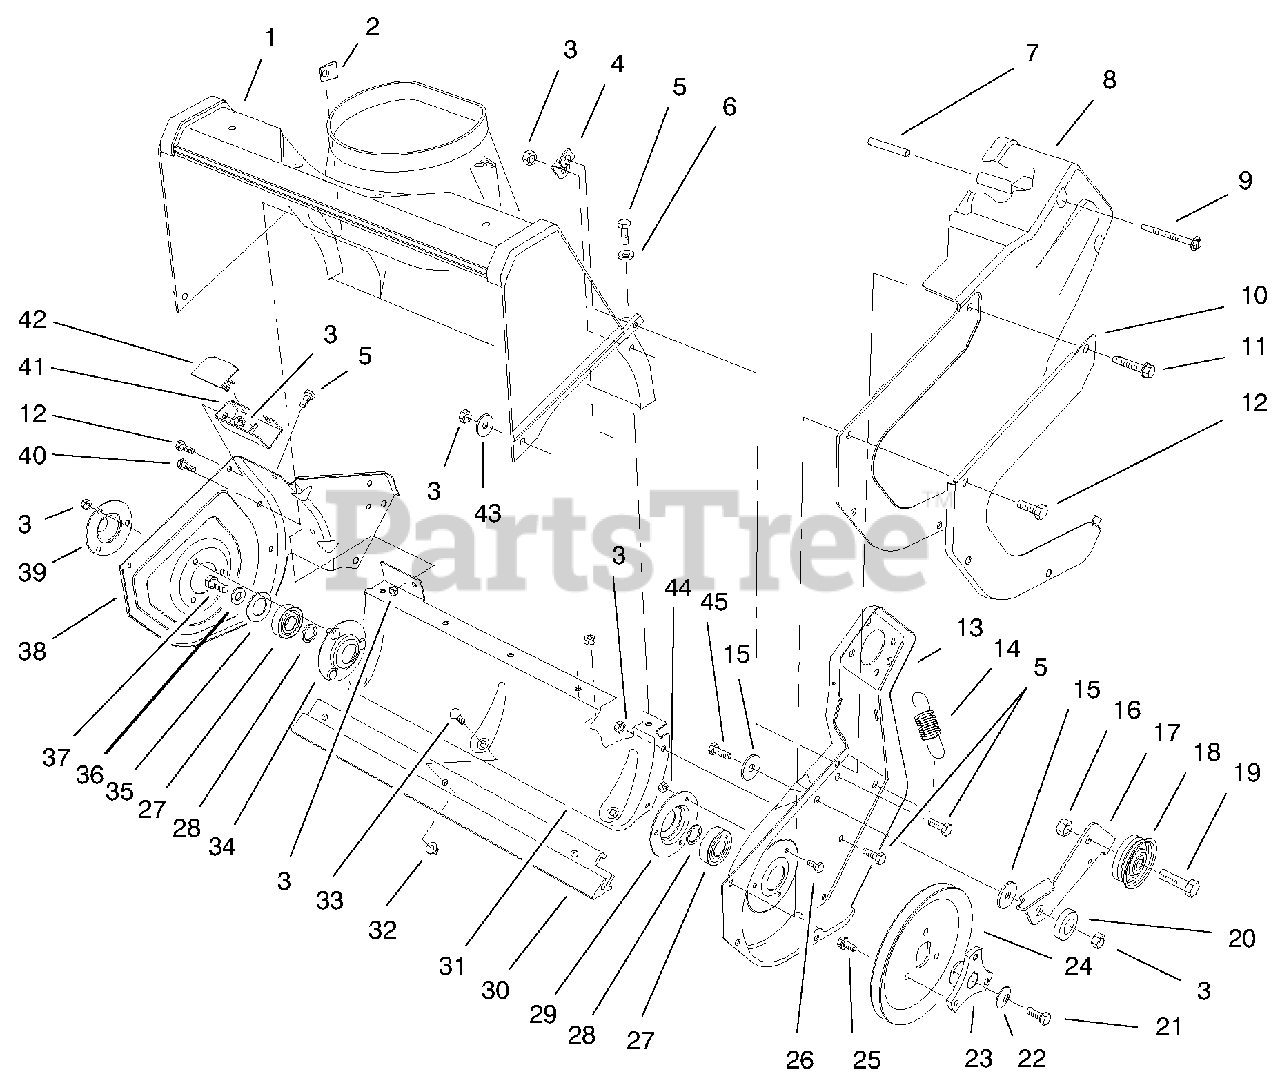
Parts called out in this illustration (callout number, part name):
3	Nut-Lock
5	Screw-HH
6	Washer-Flat
8	Cover-Drive
9	Screw-Thrd Forming
10	Guard-Edge
13	Sideplate-Left
14	Spring-Brake
15	Washer-Flat
16	Nut-Lock
17	Ilder-Brake Arm
18	Pulley-Idler
19	Screw-HH
21	Screw-HH
22	Washer-Lock
23	Hub-Mounting
24	Pulley-Rotor
25	Screw-HH
27	Bearing-Ball
28	Washer-Thrust
29	Retainer-Bearing
31	Housing-Lower
32	Nut-Lock HHF
33	Bolt-CARR
35	Washer-Rubber
36	Washer-Flat
37	Bolt-Flange
38	Sideplate-RH
39	Retainer-Bearing
40	Screw-HH
41	Bracket-Support
42	Cover-Bracket
43	Washer-Flat
44	Nut-Lock
45	Screw-HH
